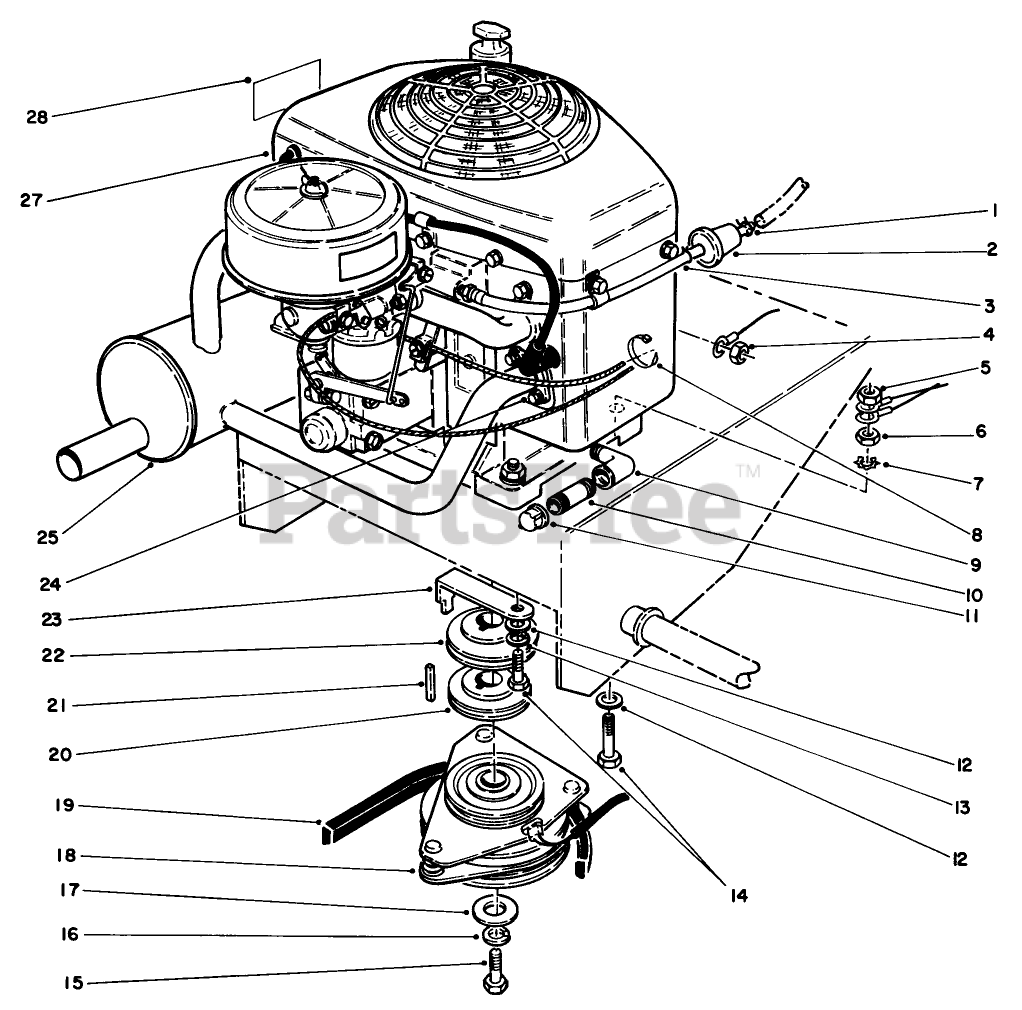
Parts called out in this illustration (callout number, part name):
1	CLAMP-HOSE
2	Fuel-Filter
3	Hose-Gas
4	NUT-KEPS
5	NUT-KEPS
6	NUT-LOCK, CONE
7	WASHER-LOCK
8	TIE-CABLE
9	ELBOW-STREET, 90 DEG
10	NIPPLE
11	CAP-PIPE
12	WASHER-PLAIN
13	WASHER-LOCK
14	SCREW-HH
15	SCREW-HH
16	WASHER-LOCK
19	V-BELT, DRIVE
20	SHEAVE-HALF, LOWER
21	KEY-SQUARE
22	SHEAVE-HALF, UPPER
24	SCREW-HSH
28	DECAL-SURFACE, HOT
